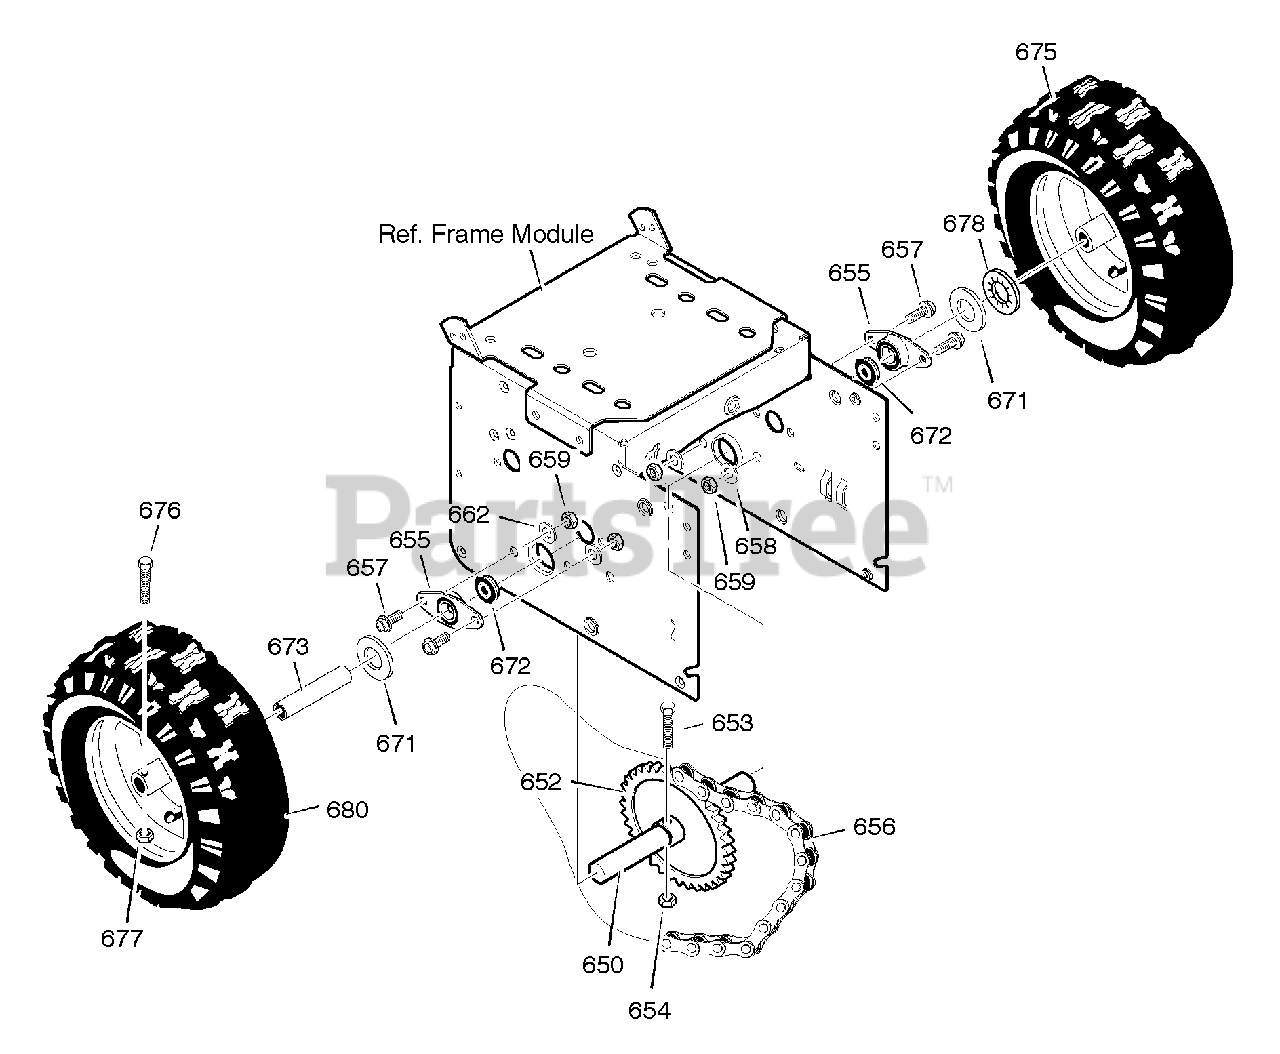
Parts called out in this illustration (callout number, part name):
650	SHAFT, AXLE
652	SPROCKET, AXLE
653	SCREW, 1/4-20X1.75
654	NUT, 1/4-20 HEX NYLOCK
655	RETAINER, BEARING
657	SCREW, .38-16x0.75
658	WASHER, LOCK
659	NUT, 3/8"-16
671	WASHER, FLAT
672	BEARING, BALL
673	BUSHING, WHEEL
675	TIRE & RIM, LEFT
676	BOLT, .25-20x1.75
677	NUT, 1/4-20 HEX NYLOCK
678	RING, RET
680	TIRE & RIM, RIGHT
